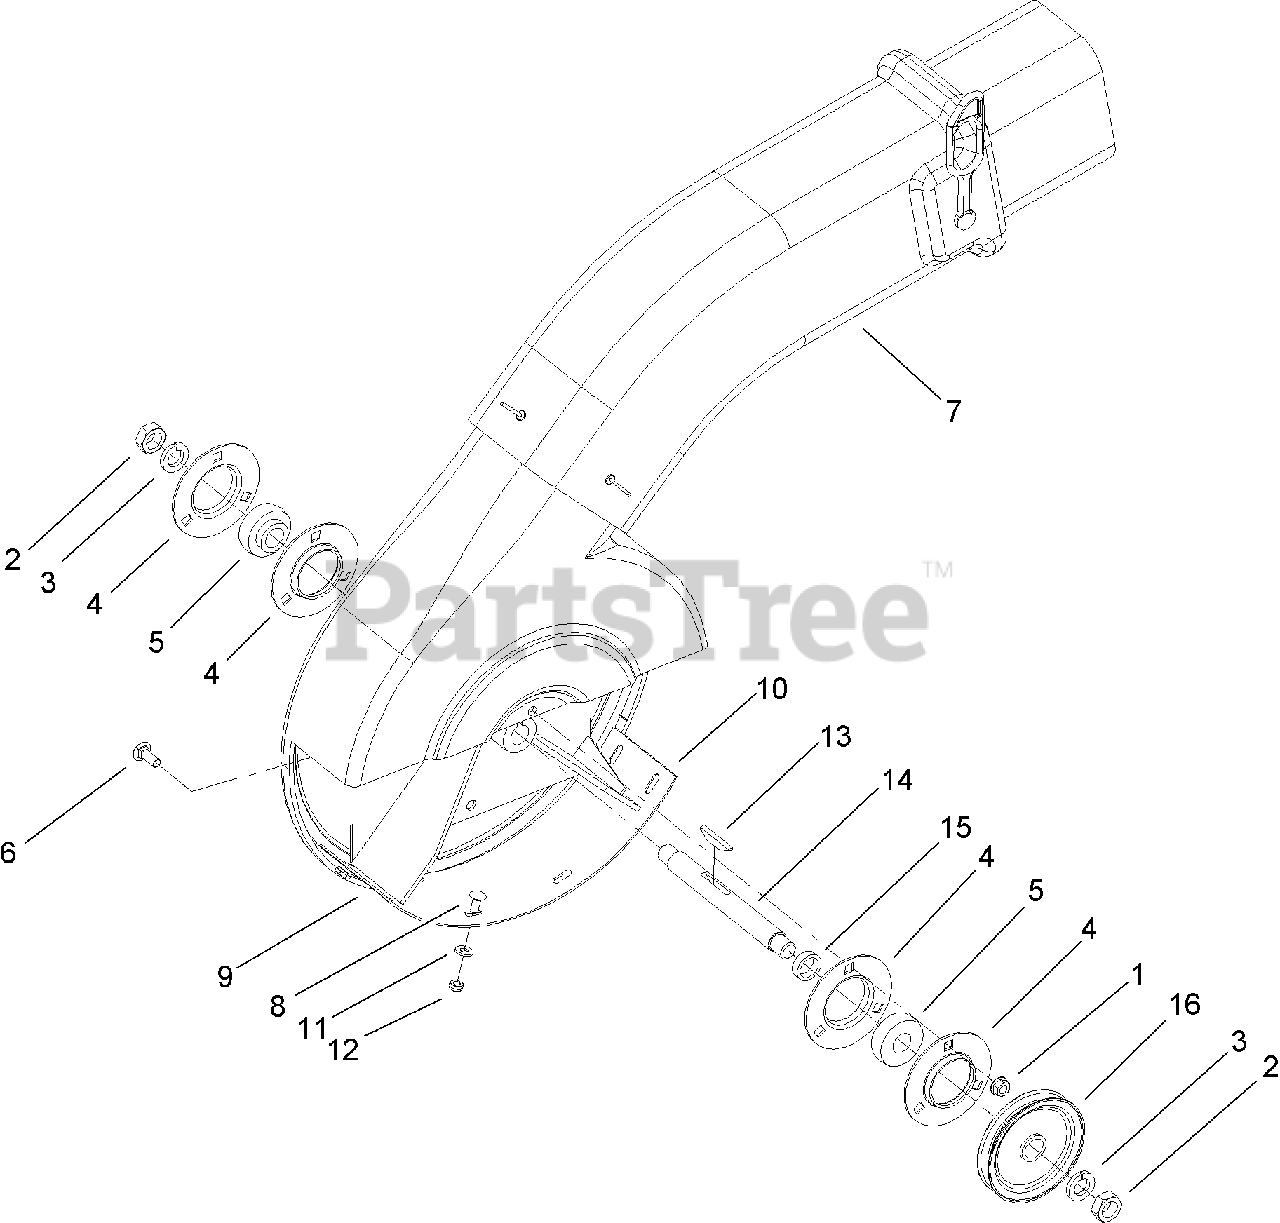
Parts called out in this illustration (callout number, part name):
2	NUT-JAM
3	WASHER-LOCK
5	BEARING-BALL
6	SCREW-CARR
7	BLOWER HOUSING/TUBE ASM
8	SCREW-CARR
9	IMPELLER ASM
10	Cover-Blower, Bottom
11	WASHER-FLAT
12	NUT-LOCK, NI
13	KEY-HI PRO
14	SHAFT-BLOWER
15	Spacer
16	PULLEY-BLOWER
